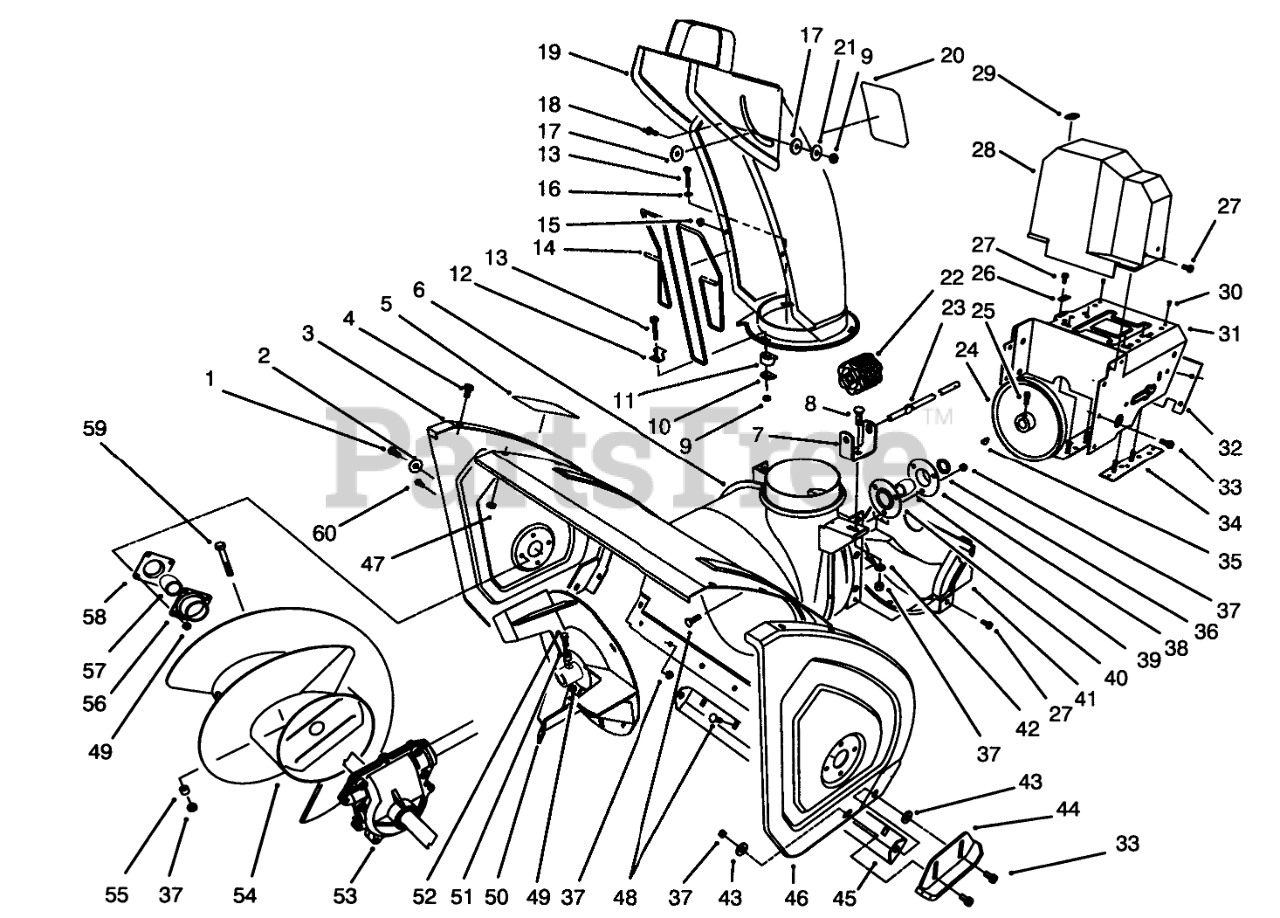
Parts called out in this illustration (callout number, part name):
1	SCREW-HH
2	WASHER
3	Plate-Side
4	SCREW-HHF
5	DECAL-WARNING, AUGER
6	Housing-24"
7	BRACKET-WORM, CHUTE
8	BOLT-CARR
9	NUT-LOCK, NI
10	PLATE-RETAINER, CHUTE
11	RETAINER-CHUTE
12	CLIP-GUARD, CHUTE
13	SCREW-HSH
14	GUARD-CHUTE
15	NUT-PUSH
16	WASHER-FLAT
17	WASHER-PLASTIC
19	Assembly
20	Decal-Danger
21	WASHER-FLAT
22	GEAR-WORM
23	ROD-CHUTE, LOWER
24	PULLEY-IMPELLER
25	SCREW-SET, SQH
26	RETAINER-CABLE
27	SCREW-HWH
28	COVER-BELT, UPPER
29	COVER-CABLE
30	RIVET-POP
31	ENGINE FRAME WA R
32	Cover-Frame, Engine
33	SCREW-HHF
34	PLATE ASM FRM LH 8 B&S
35	KEY-WOODRUFF
36	WASHER-THRUST
37	NUT-LOCK, NI
38	Flange-Bearing (Rear)
39	BEARING-BALL
40	Flange-Bearing (Front)
41	COVER-BELT, LOWER
42	WASHER-PLAIN
43	WASHER
44	Skid
45	Blade-Scraper
46	Plate-Side
47	NUT-LOCK, NI
48	SCREW-CARR
49	NUT-LOCK, NI
50	Impeller
51	SPACER
52	SCREW-HHF
53	AUGER GEARCASE ASM
54	R/H 28"AUGER WA B
55	SPACER-HUB, AUGER
56	BEARING-FLANGE, FRONT
57	BEARING
58	BEARING-FLANGE, REAR
59	Auger Bolt
60	SCREW-HH
